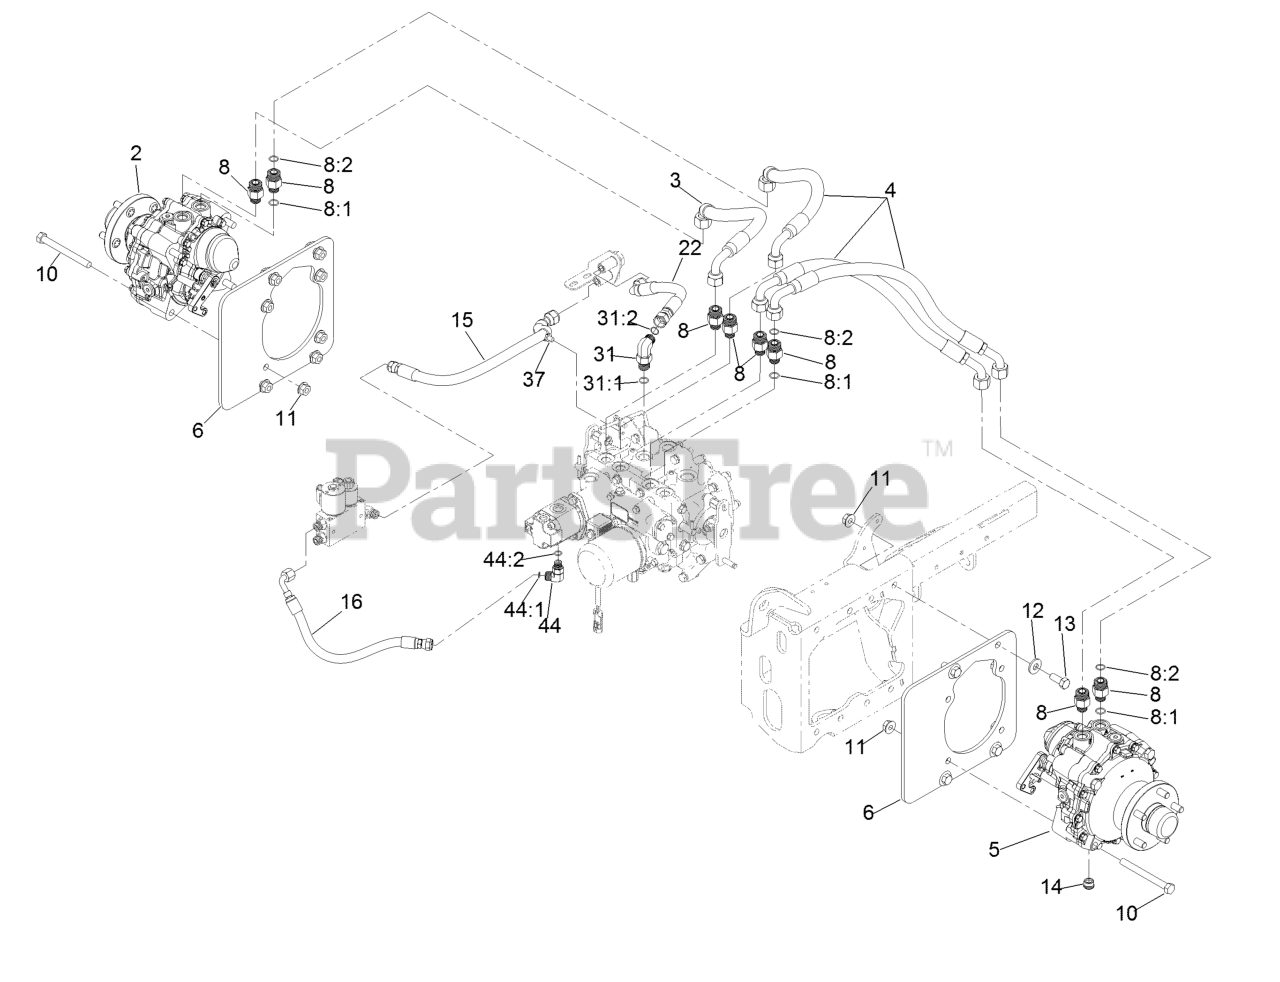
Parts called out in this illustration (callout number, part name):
2	Motor-HYD, RH
3	Hose ASM
4	Hose ASM
5	Motor-HYD, LH
6	Plate-Motor
8	Fitting-Straight
8:1	O-Ring
10	Screw-HH 1/2-13 X 5
11	Nut-Whizlock 1/2-13
12	Washer-Spring Disc 1/2
13	Screw-HH 1/2-13 X 1 1/4
14	Plug-Magnetic
15	Hose ASM
16	Hose ASM
22	Hose ASM
31	Fitting-Elbow, 90 DEG
31:1	O-Ring
31:2	O-Ring
37	Clip-Tie
44	Fitting-Elbow, 90 DEG
44:1	O-Ring
44:2	O-Ring
